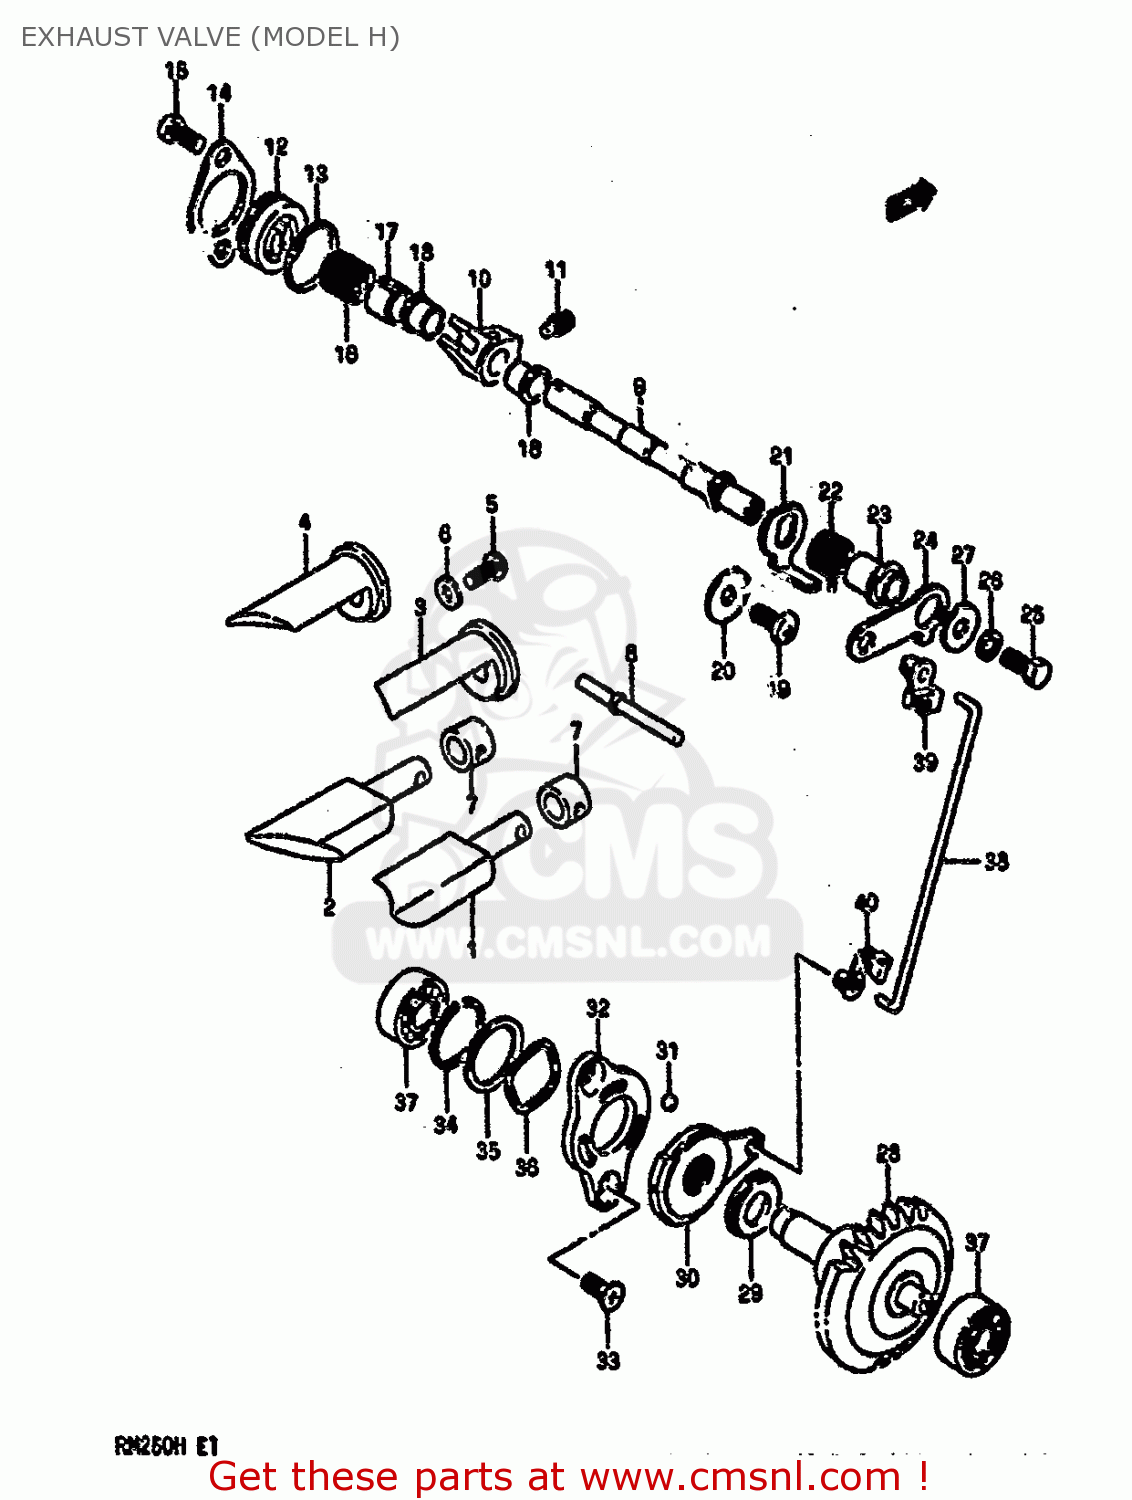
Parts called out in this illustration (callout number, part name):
1	VALVE,EXHAUST
2	VALVE,EXHAUST
3	GUIDE,EXHAUST VALVE
4	GUIDE,EXHAUST VALVE
5	SCREW
6	WASHER
7	HOLDER,EXHAUST VALVE
8	PIN,EXHAUST VALVE. 43.6MM
9	SHAFT,EXHAUST VALVE
10	ARM,EXHAUST VALVE SHAFT
11	SCREW
12	CAP,EXHAUST VALVE
13	O RING(D:1.9,ID:22.6)
14	RETAINER,EXHAUST VALVE
15	SCREW
16	SPRING
17	SPACER,EXHAUST VALVE SPRING
18	BUSH
19	SCREW 6X12
20	WASHER
21	LEVER,EXHAUST VALVE NO
22	SPRING
23	SPACER,EXHAUST VALVE
24	LEVER,EXHAUST VALVE NO
25	BOLT
26	LOCK WASHER
27	WASHER (5.5X16X1.2)
28	GOVERNOR ASSEMBLY,EXHAUST
29	BEARING(10X22X2.8)
30	ACTUATOR,EXHAUST VALVE
31	BALL
32	STARTER,EXHAUST VALVE ACTUATOR
33	SCREW(5X10)
34	CIRCLIP
35	SHIM(19.1X25X0.3)
36	WASHER
37	BEARING(8X22X7)
38	ROD,EXHAUST VALVE
39	BUSH,EXHAUST VALVE ROD NO.1
40	BUSH,EXHAUST VALVE ROD NO.2
